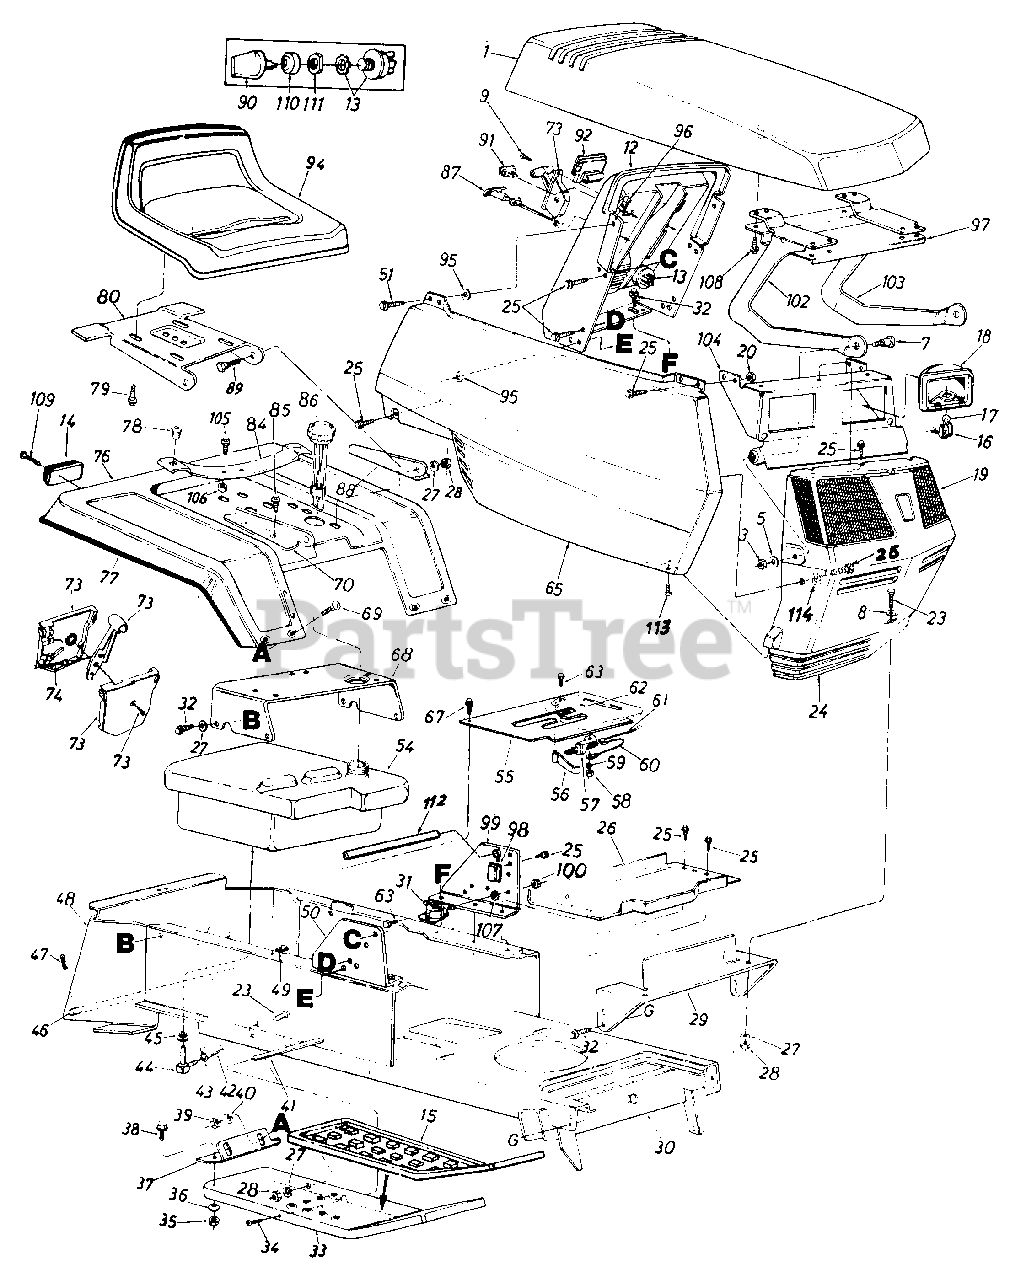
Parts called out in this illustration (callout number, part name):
5	Fl-Wash. 5/16" I.D. x 5/8" O.D.
7	Shld. Bolt .437" Dia. x .35"
8	Fl-Wash..344" I.D.
9	Truss Mach. AB-Tap Scr. #10 x .50" Lg.
12	Dash Ass'y.
13	Ignition Switch
14	Taillight
15	Foot Pad
16	Socket
17	Lamp
18	Headlight Housing
19	Lens-R.H.
20	Hex L-Nut 1/4-20 Thd.
23	Hex Bolt 5/16-18 x .75" Lg.
24	Grille
25	Hex Wash. Hd. Scr. 1/4" x .50" Lg.
26	Batery Plate
27	L-Wash. 5/16" I.D.
28	Hex Nut 5/16-18 Thd.
29	Grille Mounting Bracket
30	Lower Frame Ass'y.
31	Solenoid
32	Hex Thd. Rolling Scr. 5/16-24 x .75" Lg.
33	Running Board-R.H.
34	Truss Mach. Scr. 5/16-18 x .75" Lg.
35	Hex Nut 5/16-18 Thd.*
36	Bell-Wash. .34" I.D. x .87"
39	Hex Nut 1/4-20 Thd.
40	L-Wash. 1/4" I.D.
41	Running Board Rod
42	Fuel Line 40" Lg.
43	Hose Clamp 3/8"
44	90ø Nipple
45	Bushing
46	Hitch Rod
47	Internal Coterpin
48	Hitch Plate
49	Speed Nut
50	Dash Support Brkt. R.H.
51	Hex Wash. Hd. Tap Scr. 1/4 x .75" Lg.
54	Fuel Tank
55	Transmission Cover Ass'y.
56	Switch Actuator Lever
57	Safety Switch
58	Hex Nut 1/4-20 Thd.*
59	L-Wash. 1/4" I.D.
60	Electric Wire
61	Reverse Lockout Wire Harness
62	Snap Bushing
63	Hex Bolt 1/4-20 x .50" Lg.
65	Side Panel Ass'y. R.H.
67	Truss Mach. "B" Tap Scr. #10 x .50" Lg.
68	Seat Mounting Channel
69	Carriage Bolt 1/4-20 x .50"
70	Seat Bracket-R.H.
73	Throtle Control Box Ass'y.
74	Throtle Control Wire
76	Rear Fender
77	Trim Strip-81" Lg.
78	Grommet
79	Hex Wash. Hd. AB-Tap Scr. 318 x .75" Lg.
80	Seat Pivot Bracket
84	Seat Spring
85	Hex Wash. Hd. Self-Tap Scr. 5/16-18 x .50" Lg.
86	Gas Cap w/Gauge
87	Choke Control Comp.
88	Seat Bracket-L.H.
89	Shld. Bolt .437" Dia. x .162"
90	Ignition Key
91	Light Switch
92	Ammeter
94	Seat Ass'y.Black Trim
95	Pushnut Fastener
96	Speed Nut 1/4-20 Thd.
97	Hood Reinforcement
98	Circuit Breaker
99	Dash Support Brkt.L.H.
100	Hex Sems Nut 1/4-20 Thd.
102	Hood Hinge-R.H.
103	Hood Hinge-L.H.
106	Spacer.38" I.D.
107	Ext. L-Wash. .44" I.D.
108	Hex Wash. B-Tap Scr. 1/4 x.62" Lg.
109	Truss Hd. AB-Tap Scr. #6 x .62" Lg.
110	Ignition Switch Cap
111	Ignition Switch Nut
112	Dash Support
113	Hex AB-Tap Scr. #10 x .5"
114	Fl- Wash. 1/4" I.D.
